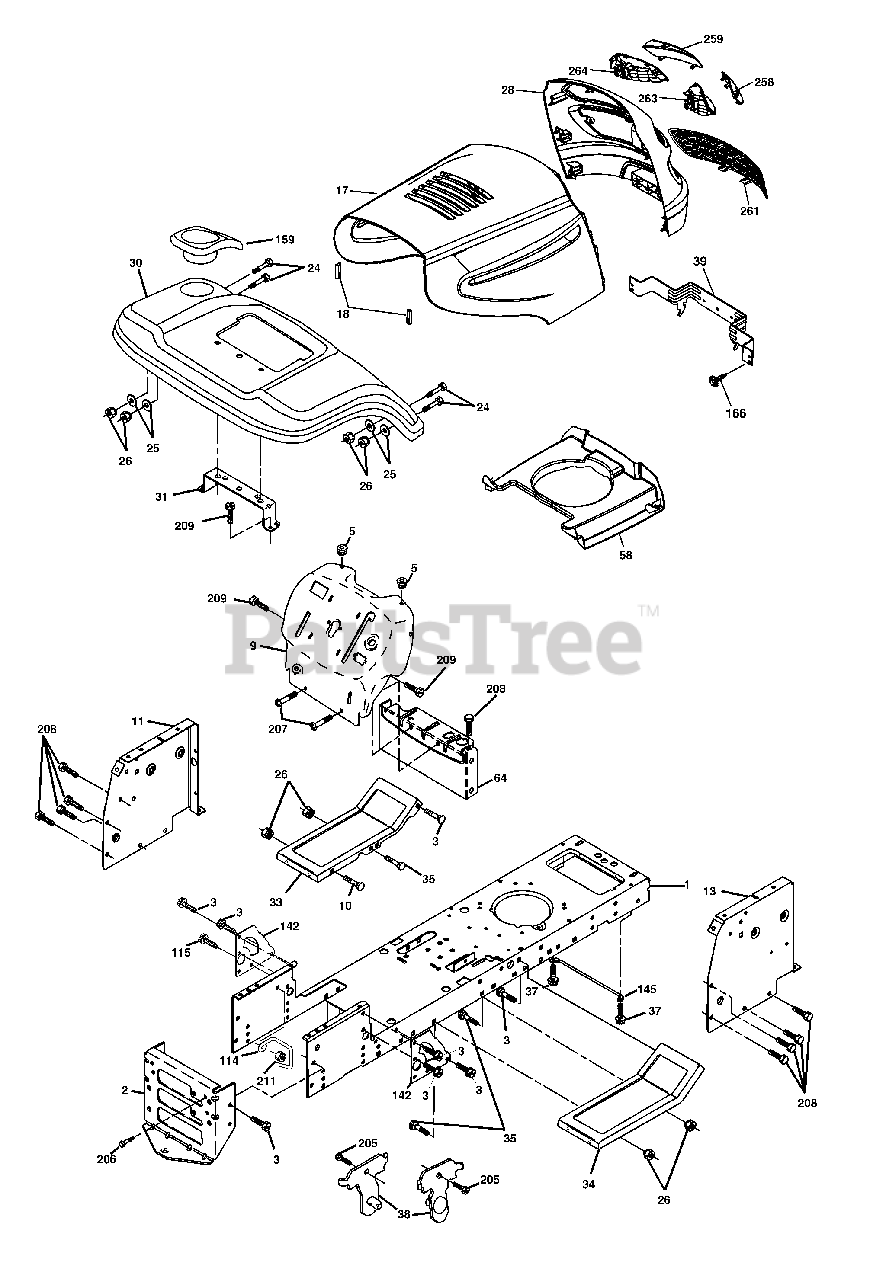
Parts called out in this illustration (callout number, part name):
1	Chassis
2	Drawbar
3	Screw 3/8-16 x 3/4
5	Bumper Hood/Dash
9	Dash
10	Bolt Rd Hd Sqnk. 3/8-16 Unc x 1
11	Panel Asm. Dash Lh
13	Panel Dash Rh
17	Hood
18	Bumper Hood
24	Bolt Fin Hex 3/8-16 Unc x 1 Gr. 5
25	Washer 13/32 x 13/16 x 12 Ga.
26	Nut Lock Hex w/Insert 3/8-16 Unc
28	Grill/Lens Asm
30	Fender Asm
31	Bracket Fender
33	Footrest LH
34	Footrest RH
35	Bolt Rd Hd Sht. Sqnk. 3/8-16 x 3/4
37	Screw Thdrol 5/16-18 x 1/2 Tyt
38	Bracket Asm. Pivot Mower Rear
39	Bracket Pivot
58	Air Duct
64	Dash Lower
114	Keeper Belt Rear LH
115	Screw Thdrol 3/8-16 x 1-1/4
142	Plate Reinforcement
145	Rod Pivot Chassis/Hood
159	Cupholder
166	Screw #13-16 x 3/4
205	Screw Thdrol 3/8-16 x 1/2
206	Bolt shoulder 5/16-18
207	Screw Thdrol 5/16-18 x 1/2
208	Screw Thdrol 3/8-16 x 1/2
209	Screw 3/8-16 x 3/4
211	Nut Hex flange Lock
258	Lens Grille RH
259	Lens Grille LH
263	Bezel Grille LH
264	Bezel Grille RH
